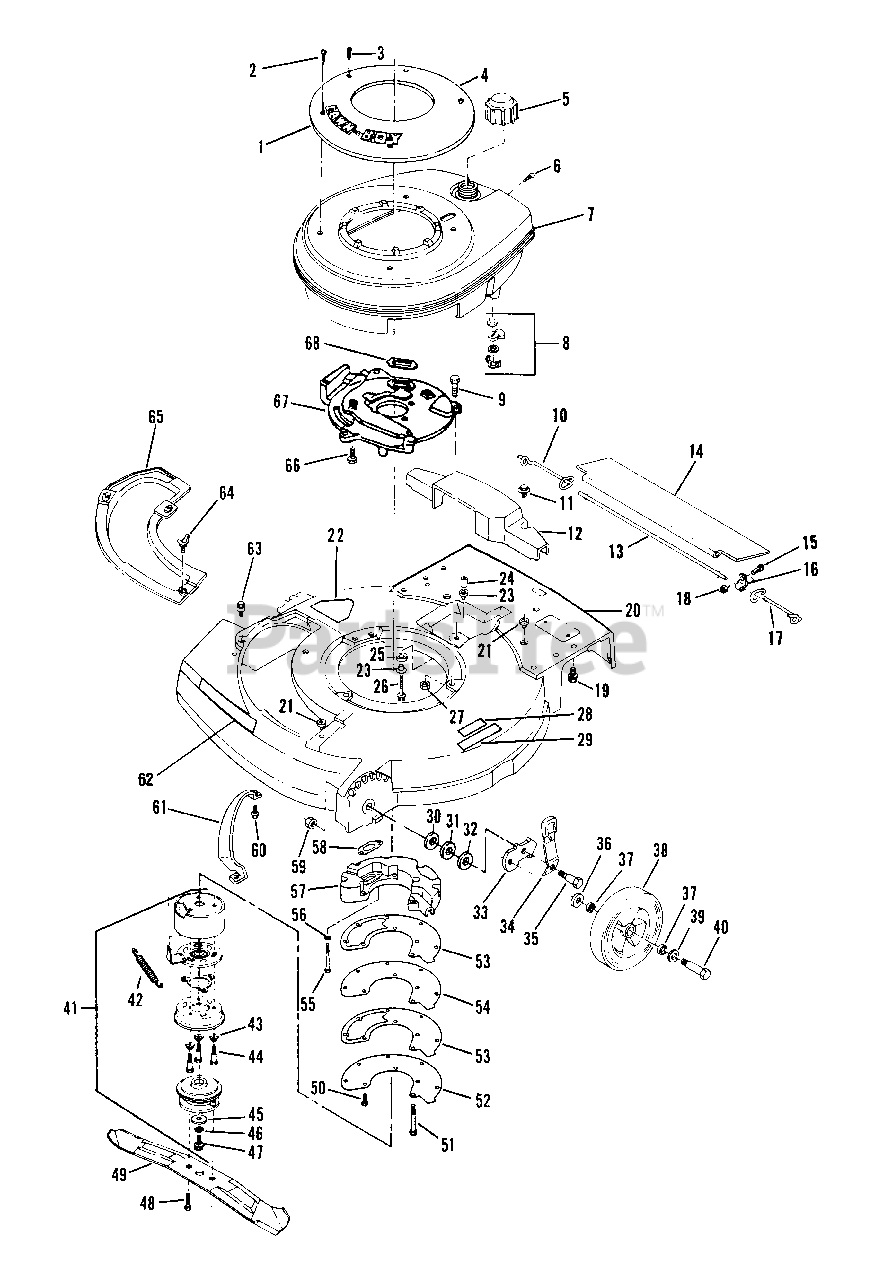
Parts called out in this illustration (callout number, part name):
1	Decal-Lawn-Boy
2	Screw
3	Screw-Starter Mounting
4	Starter Base and Nut Assembly
5	Fuel Cap
6	Screw-Shroud to C.D. Bracket
7	Shroud-Engine
8	Fuel Shut-Off Assembly
9	Screw-Muffler Plate to Housing
10	Spring-R.H.
11	Screw-Axle Cover Mounting
12	Cover-Drive Axle
13	Rod-Trailing Shield
14	Shield-Trailing
15	Screw
16	Clamp
17	Spring-L.H.
18	Nut-Trailing Shield
19	Screw-Handle Bracket
20	Housing
21	Grommet
22	Decal-Blade Contact Warning
23	Spacer
24	Spacer
25	Grommet
26	Screw
27	Nut-Muffler Plate to Housing
28	Decal-Starting Pad
29	Pad-Starting
30	Washer
31	Washer-Shim-Wheel Height Adjust Bracket
32	Washer-Shim-Wheel Height Adjust Bracket
33	Bracket-Wheel Height Adjust
34	Knob and Spring Assembly
35	Bolt-Shoulder
36	Washer
37	Washer-Felt
38	Wheel-Front
39	Washer
40	Bolt-Wheel-Front
41	Clutch Brake Assembly
42	Spring
43	Spring Pressure
44	Screw-Shoulder
45	Washer
46	Lockwasher
47	Screw
48	Screw-Sems-Blade
49	Blade-21"
50	Screw
51	Screw
52	Cover
53	Gasket
54	Heat Shield
55	Screw
56	Washer
57	Muffler
58	Gasket
59	Nut
60	Screw
61	Toe Bar
62	Decal-Headliner
63	Screw-Plate and Chute Mounting
64	Wing Screw
65	Cover Plate
66	Plate-Muffler
68	Gasket-Exhaust
